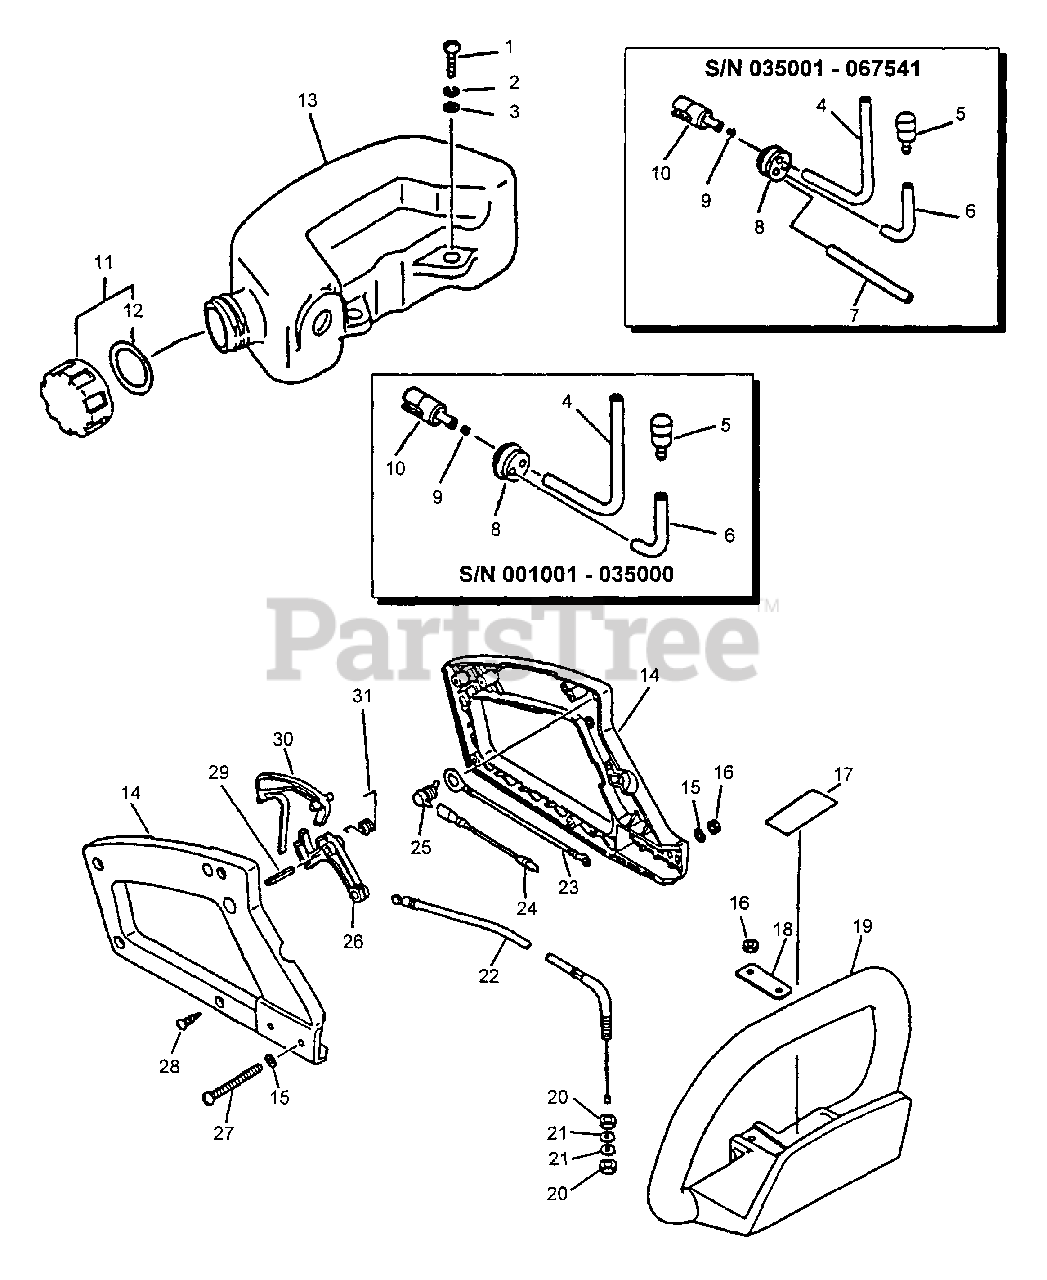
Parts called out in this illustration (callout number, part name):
1	SCREW - 5X16
2	LOCKWASHER - 5
3	WASHER - 5
4	PIPE - 3X5X195 -- BLACK
5	VENT, FUEL TANK
6	PIPE - 3X6X70 -- CLEAR
7	PIPE - 3X6X110 -- CLEAR
8	GROMMET
9	CLIP - 6
10	FILTER, FUEL
11	CAP ASSY
12	GASKET, CAP
13	TANK, FUEL
14	HANDLE ASSY - REAR
15	WASHER - 5
16	LOCKNUT - 5
17	LABEL - CAUTION
19	HANDLE - FRONT
20	WASHER - 6
22	CABLE, THROTTLE
23	LEAD - GROUND
24	LEAD - GROUND
25	IGNITION SWITCH ASSY
26	TRIGGER, THROTTLE
27	SCREW - 5X55
28	SCREW - 4X16
29	PIN - SPRING -- 5X25
30	LOCKOUT, THROTTLE
31	SPRING, TRIGGER
